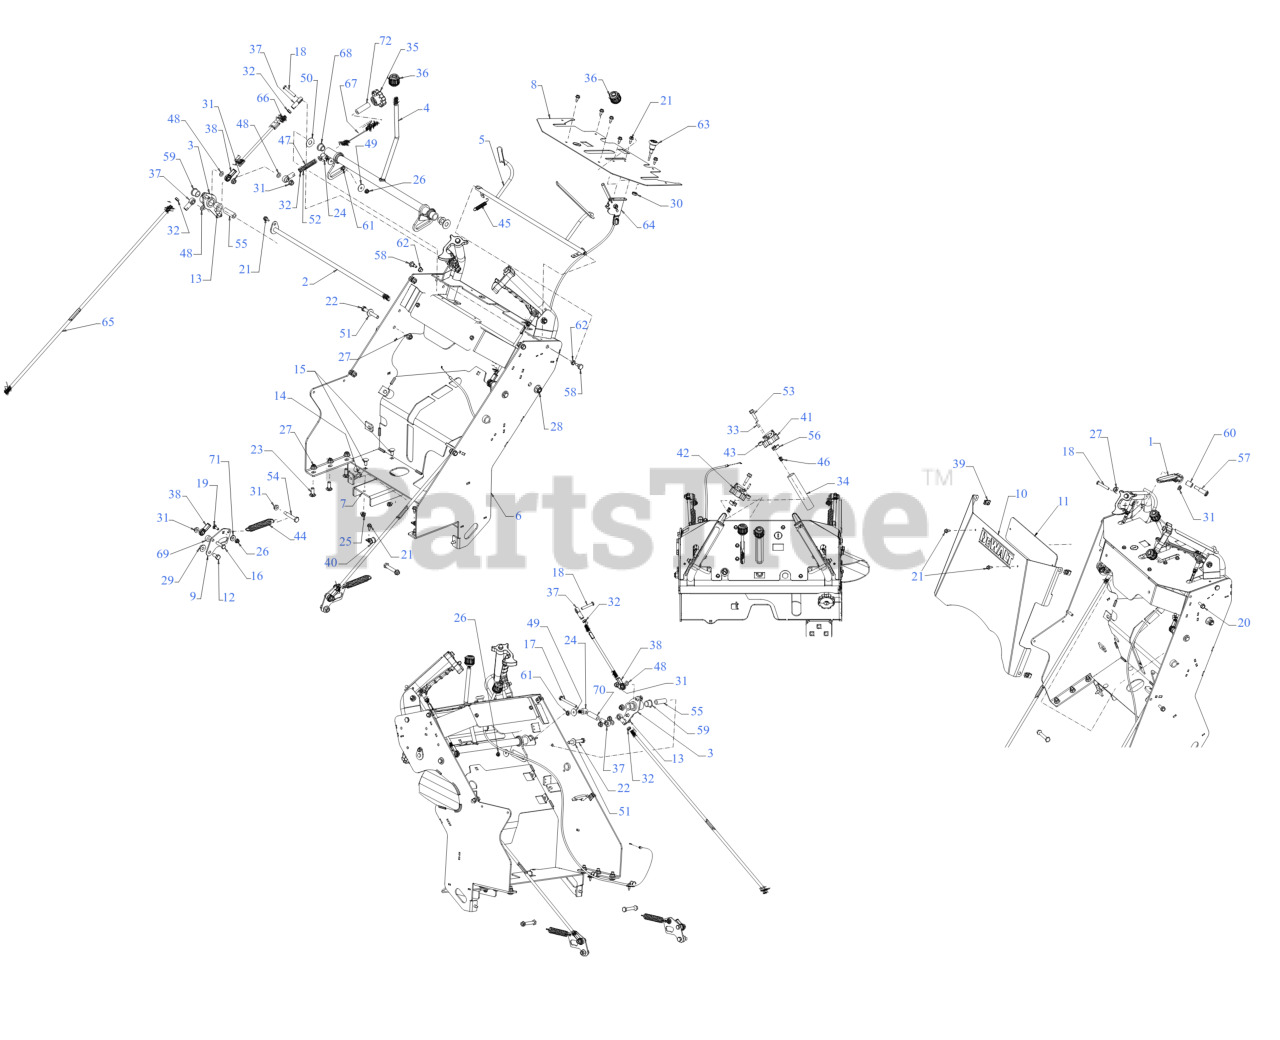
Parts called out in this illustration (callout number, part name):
1	BRAKE HANDLE
2	CONTROL PIVOT WELDMENT
3	BELLCRANK ASSEMBLY
4	CRUISE CONTROL ASSEMBLY
5	BAIL ASSEMBLY
6	HANDLE CONTROL ASSEMBLY
7	PEDAL BRACKET
8	CONTROL PANEL
9	TRANSMISSION CONTROL BRACKET
10	UPPER HANDLE COVER
11	BACK PLATE
12	HEX SCREW 3/8-16 x .75
13	CARRIAGE BOLT 5/16-18 x 1.00
14	SCREW 5/16-18 x .750
15	CARRIAGE BOLT 5/16-18 x .75
16	SCREW 5/16-18 x 1.25 GR5
17	SCREW (5/16-24:3.00:GR5)
18	SCREW (5/16-18:1.7)
19	SCREW 1/4-20 x .75 GR5
20	SCREW 5/16-18 x .875 GR5
21	SCREW 1/4-20X.625
22	SCREW 3/8-16 x 2.75 GR5
23	CARRIAGE BOLT 3/8-16 x 1.00 GR5
24	FURRLE (.328 ID x .250)
25	FLANGE LOCK NUT 5/16-18
26	FLANGE LOCK NUT
29	FLANGE LOCK NUT
30	HEX JAM NUT 3/8X24
31	HEX FLANGE NUT
32	HEX JAM NUT 5/16-24 GR 5
33	DOWEL PIN
34	GRIP (1.0 ID x 5.5 x .065)
35	KNOB (5/16-24) (LH)
36	BALL KNOB
37	ROD END 5/16 ID
38	END ROD- 5/16 (LH)
39	U-NUT 5/16-18
40	CLAMP
41	HANDLE LOCK (RH)
42	HANDLE LOCK (LH)
43	NEUTRAL LOCK ROLLER
44	EXTENSION SPRING
45	EXTENSION SPRING
46	NEUTRAL LOCK SPRING
47	TRACKING SPRING
48	FLAT WASHER .344 x .62
49	FLAT WASHER
50	FLAT WASHER (0.526X1.250X0.048)
51	WASHER
52	FLAT WASHER ID-.320 x .598
53	SHOULDER SCREW
54	SHOULDER SCREW
55	BELLCRANK SPACER
56	NEUTRAL LOCK SPACER
57	SHOULDER SCREW .50X.925
58	SHOULDER SCREW .375 x X .380 x 1/4-20
59	FLANGE BEARING
60	SLEEVE BEARING .623 x .5025 x .250
61	BALL BEARING .25 x .625 SPCL
62	FLANGE BEARING .375X.580X.250
63	CHOKE CABLE
64	THROTTLE CABLE
65	TRANSMISSION CONTROL ROD
66	CONTROL LEVER ROD
67	CONTROL TRACKNG ROD
68	FLANGE BEARING .503ID
69	IDLER BRACKET SPACER .340X.750X.330
70	SPACER (.322 x .625 x 1.8)
71	TRANSMISSION SPACER
72	SPACER
